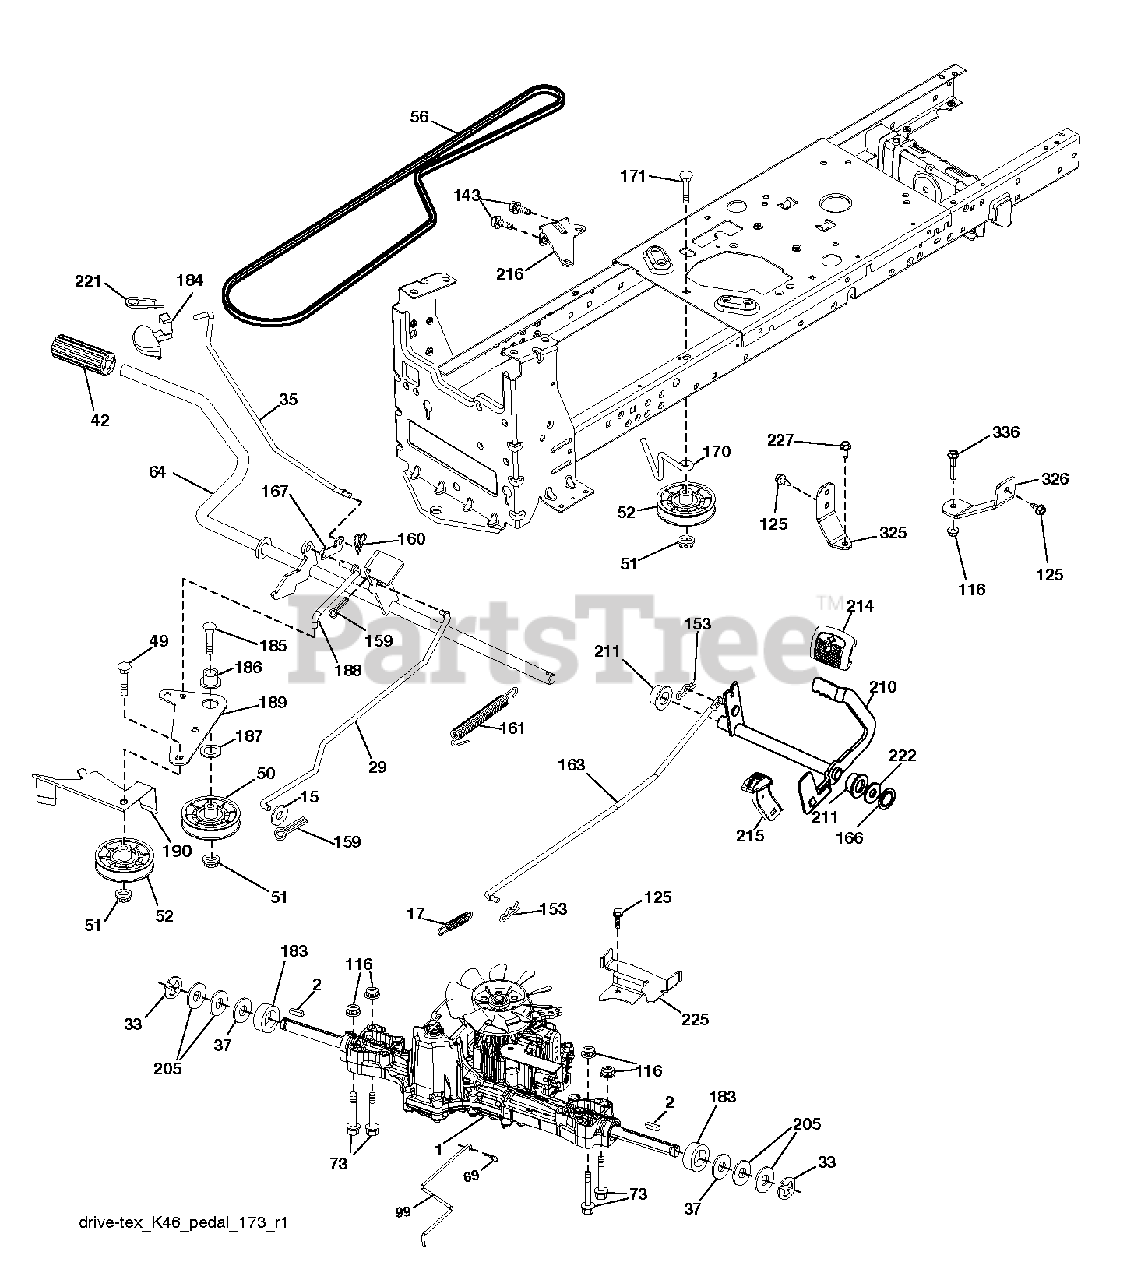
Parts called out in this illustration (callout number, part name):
2	SQUARE KEY
15	WASHER
17	SPRING.BRAKE.K46.GREEN
29	ROD.BRAKE.K46
35	ROD ROD.PARKINGBRAKE.GT.HUSQ/P
37	WASHER.HARDENED
42	PEDAL COVER T
50	IDLER.FLAT.910.OFFSET
51	NUT LOCK FLG 3/8-16 UNC
52	IDLER.V-GROOVE.910.OFFSET
56	V-BELT.MOWER.92.40.42/K46
64	SHAFT.ASM.PEDAL.BRK.CNTR
69	HAIRPIN.SOFT.ZINC.059X1.125
99	ARM.PIVOTING.TCRD.GEN2.5.BAGGE
116	NUT LOCK HEX FLANGE 5/16-18
125	SCREW
143	SCR 5/16-18 X 1/2 SELFTAP ZN
153	RETAINER M
159	COTTER PIN
160	RETAINER CLIP
161	SPRING, RETURN LT
163	ROD.CONTROL.K57R.K46
166	NUT.PUSH.625
167	LATCH.BRAKE.SPRING
170	KEEPER.V-IDLER.CENTER.
183	SPACER AXLE
184	HANDLE.PARKING.BRAKE.H (BLK)
186	SPACER.RETAINER
187	WASHER 12/32X2X10GA
188	LINK.CLUTCH.GROUND DRIVE.LONG
189	BELLCRANK.GROUND.DRIVE.TEX.
190	KEEPER.BELLCRANK.DRIVE
210	ROCKER.ASM.PEDAL.CONTR
211	BEARING.NYLON
214	PEDAL.FORWARD.PAD.TEX
215	PEDAL.COVER.REVERSE.CRD.X428BK
216	BRACKET.PULLEY.IDLER.W/TEX
221	RETAINER.SPRING.CLIP.H
222	WASHER 21/32 X 1-1/4 X 10 GA.
225	KEEPER.BELT.TRANSAXLE.K46
227	SCREW
325	BRACKET.TRQ.STP.46.20".TIRE.LH
326	BRCKT.PNT.TRQ.STP.46.20TIRE.RH
336	BOLT.5/16-18X1-3/4.FLANGED.HEX
